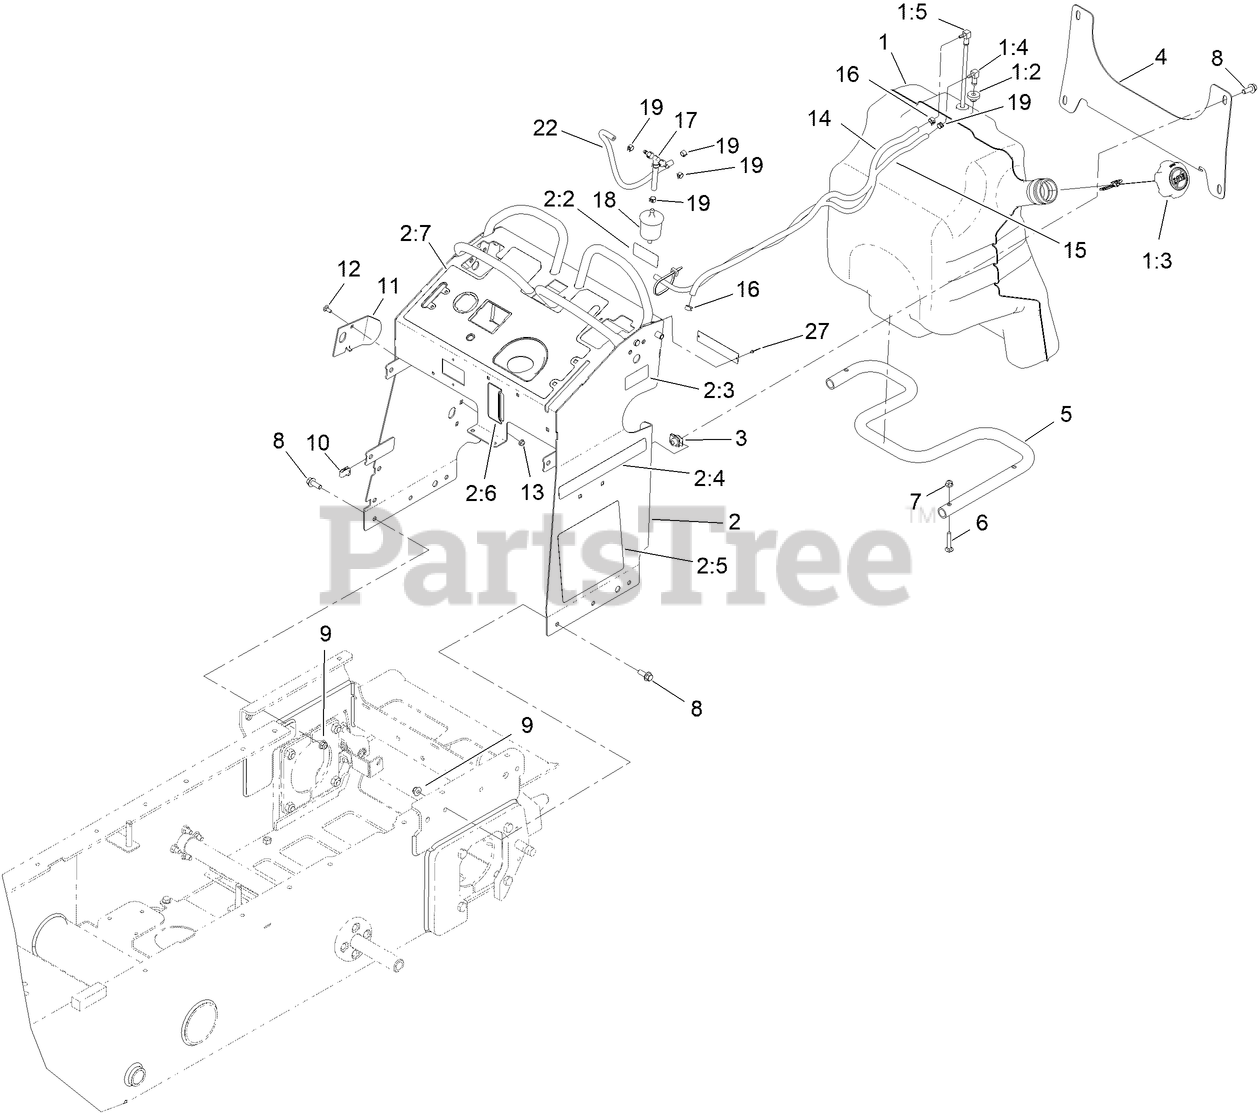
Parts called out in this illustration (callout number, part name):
1	FUEL TANK ASM
1:2	BUSHING
1:3	CAP-FUEL
1:4	FITTING-ELBOW, 90 DEG
1:5	ASM, TUBE-FUEL
2	TOWER ASM- SWIVEL
2:2	DECAL-FUSE
2:3	DECAL-FILL, FUEL
2:5	DECAL - SERVICE, MBTX-2500S
2:6	DECAL-LEVEL, OIL
2:7	DECAL-CONTROL PANEL
3	NUT-TINNERMAN
4	BRACKET-CROSS
5	TUBE-MOUNT, FUEL TANK
6	BOLT-CAR
7	NUT-HF, NI
8	SCREW-HHF
9	NUT-HF, NI
10	NUT-CLIP, U
11	PLATE-STRIKER
12	SCREW-CARR
13	NUT-HF
14	HOSE-FUEL
15	HOSE-FUEL
16	CLAMP-HOSE
17	TEE AND CHECK
18	FILTER-FUEL
19	CLAMP-HOSE
22	HOSE-VENT
